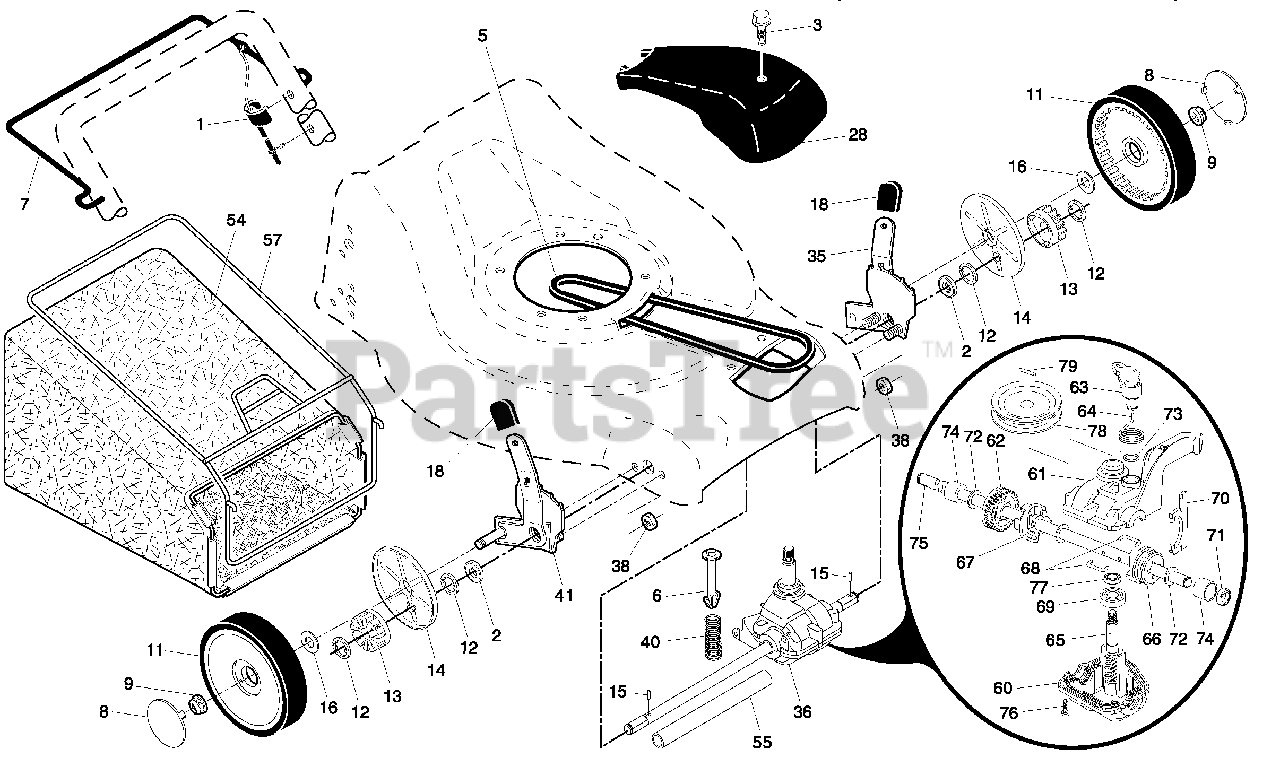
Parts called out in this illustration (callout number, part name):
1	Control Cable Assembly
2	Bearing, Wheel Adjuster
3	Pan Head Tapping Screw #10-24 x 2-3/4
5	V-Belt
6	Spring Retainer
7	Control Bar, Drive
8	Hubcap
9	Nut, Flangelock, Special Thread
11	Wheel & Tire Assembly
12	E-Ring
13	Pinion
14	Dust Cover
15	Pawl, Drive
16	Washer 1/2 x 1-1/2 x .134
18	Selector Knob
28	Dive Cover
35	Kit, Wheel Adjuster, LH
36	Gear Case Assembly, Complete
38	Locknut, Hex 1/4-20
40	Spring
41	Kit, Wheel Adjuster, RH
54	Grassbag
55	Driveshaft Cover
57	Frame, Grassbag
60	Case, Lower
61	Case, Upper
62	Gear, 27 Teeth
63	Lever, Clutch
64	Spring, Return
65	Shaft, Input
66	Dog, Movable
67	Dog, Fixed
68	Wire, Formed
69	Bearing, Ball
70	Fork, Shift
71	Seal, Output Shaft
72	Washer
73	Seal, Case
74	Bushing
75	Shaft, Output
76	Screw
77	Seal, Input Shaft
78	Drive Pulley
79	Pin, Retaining
